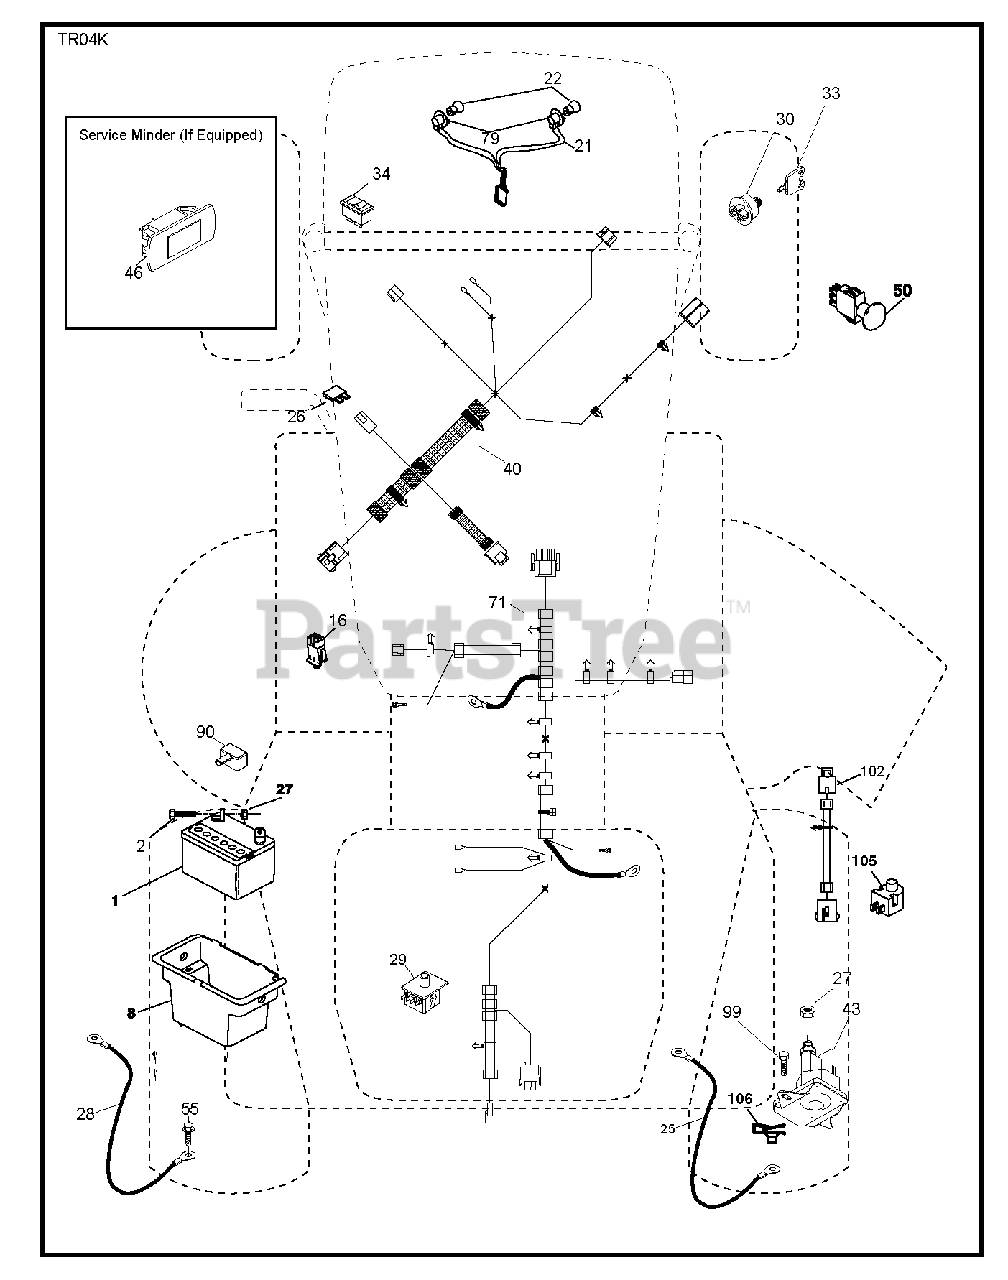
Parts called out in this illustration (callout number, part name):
1	REPL BY 532 12 38-99
2	BOLT.HEX.1/4.X.3/4.DICHROMATE
8	BOX.BATTERY.MNT.REAR.L
16	SWITCH INTERLOOK PUSH-IN
21	HARNESS.LIGHT W/4152J BULBS
22	LIGHTBULB
25	CABLE.BATT.RED.8GA.17
26	FUSE 20AMP
27	NUT
28	CABLE.GROUND.REAR.BATTERY.8G
29	SWITCH.SEAT.DP W/RAMPS
30	SWITCH.IGN.DELTA.W.LGH.ROS
33	KEY.CHAIN.BLISTER.PACK.GEN.USA
34	SWITCH LT
40	HARNESS.DASH.RRBATT.EL.CHG
43	SOLENOID.W/BRASS.PLUNGER
46	Hour Meter Gauge
50	PTO Switch, 8-Terminal STD Black
55	SCREW 5/16"
71	HARNESS.CHASSIS.RRBATT.RDYSTRT
79	BULB HOLDER ASM.
90	COVER.TERMINAL.BATTERY
99	SCREW HEXWSHR 1/4-20X3/4
102	HARNESS.PIGTAIL.VARIATOR.SD
105	REVERSE SWITCH
106	1/4-20 U NUT
